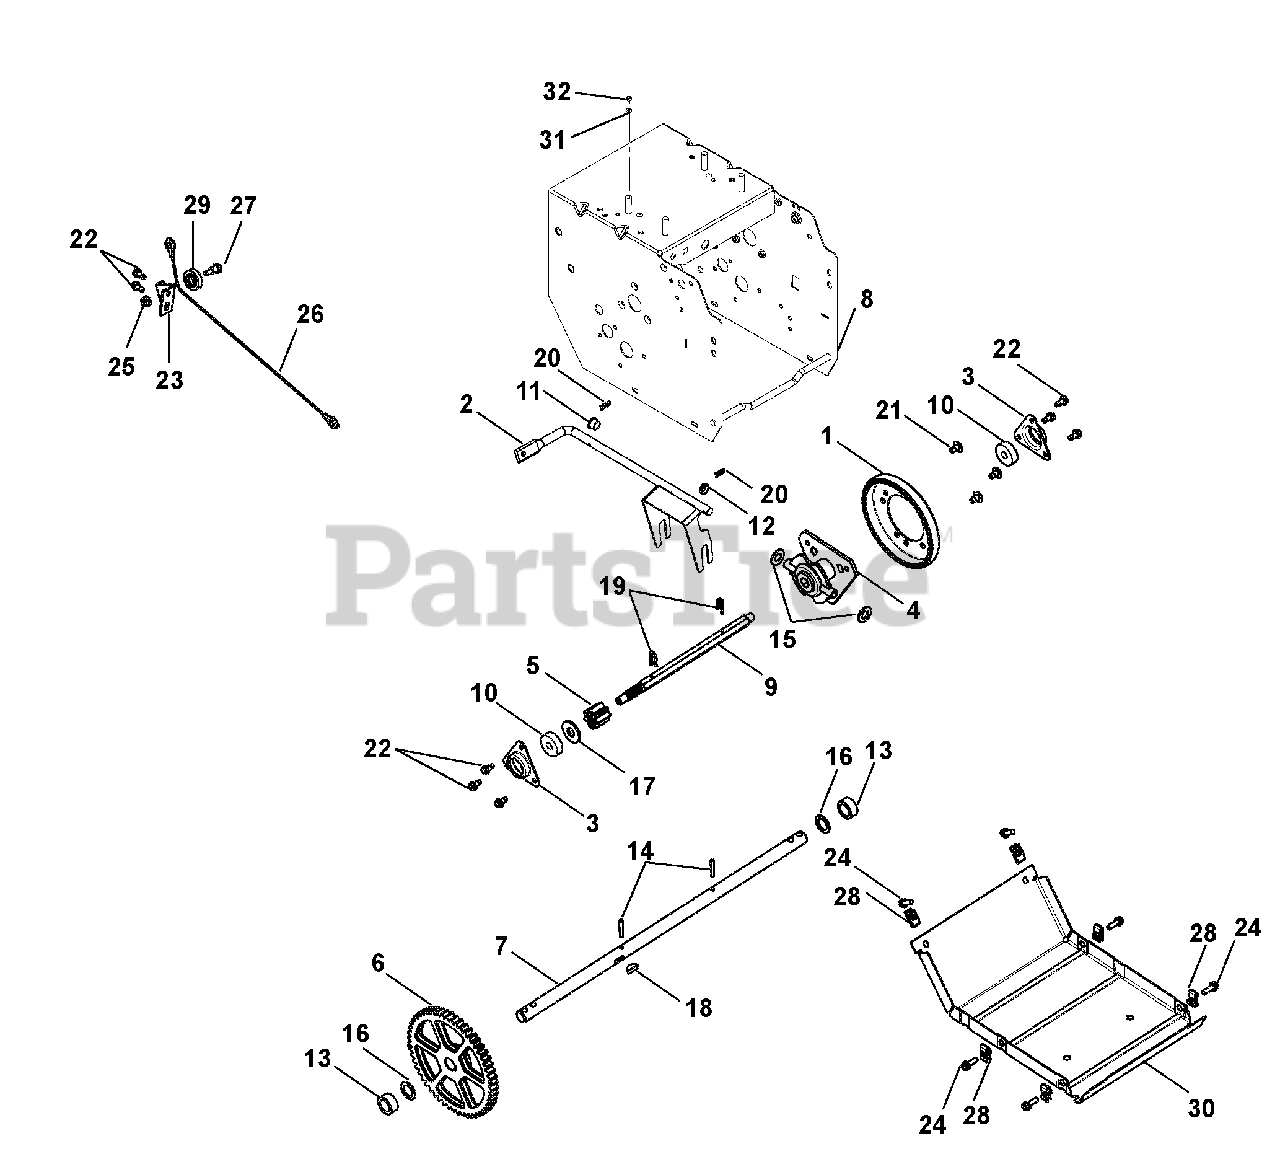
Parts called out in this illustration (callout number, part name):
1	FRICTION, DISC
2	WELDMENT, SHIFT FORK
3	FLANGE, BEARING
4	CARRIER, DRIVE DISK
5	GEAR, PINION, 7 TOOTH W/SPLINE
6	SPUR GEAR, 54T .75ID X 6.75PD
7	AXLE, COMPACT 920,XXX 15" TIRE
7	SHAFT, AXLE
8	FRAME W/ENGINE BOLT STRAPS
9	SHAFT, HEX W/SPLINE
10	BRG-BALL .437X1.375X.437
11	BUSHING, POLYLINER-.50 SPLIT
12	BUSHING, POLYLINER-.50 SNAPIN
13	BSHG-SLV .766 X 1.125 X .500
14	PIN-ROLL .188X1.25
15	WSHR-FL-STL .505X1.00X.062YWZC
16	WSHR-FL-STL.754X1.125X.062YWZC
17	@WSHR-FL-STL.563X1.38X.109YWZC
18	KEY-WDRF .25X.750X.313 SAE91
19	PIN, SPRING CLIP
20	CLIP, SPRING
21	SCR-TAP SERRDHDTX .31-18X.50BP
22	SCR-TAP .25-20X.50 HWH TR YWZ
23	BRACKET, CABLE PULLEY
24	BLT-HEX .25-20X.75 HWH YZ GR5
25	@NUT-LK-CTR-FLG .25-20 YWZC
26	CABLE, LOWER TRACTION (CMPCT)
27	BOLT, SHLDR-.375X.375X.25-20
28	NUT-RTNR .25-20X.56
29	PULLEY, CABLE
30	COVER, BOTTOM
31	WSHR-LK .312X.097 HVY YWZC
32	@NUT-HEX .31-18 YWZC
